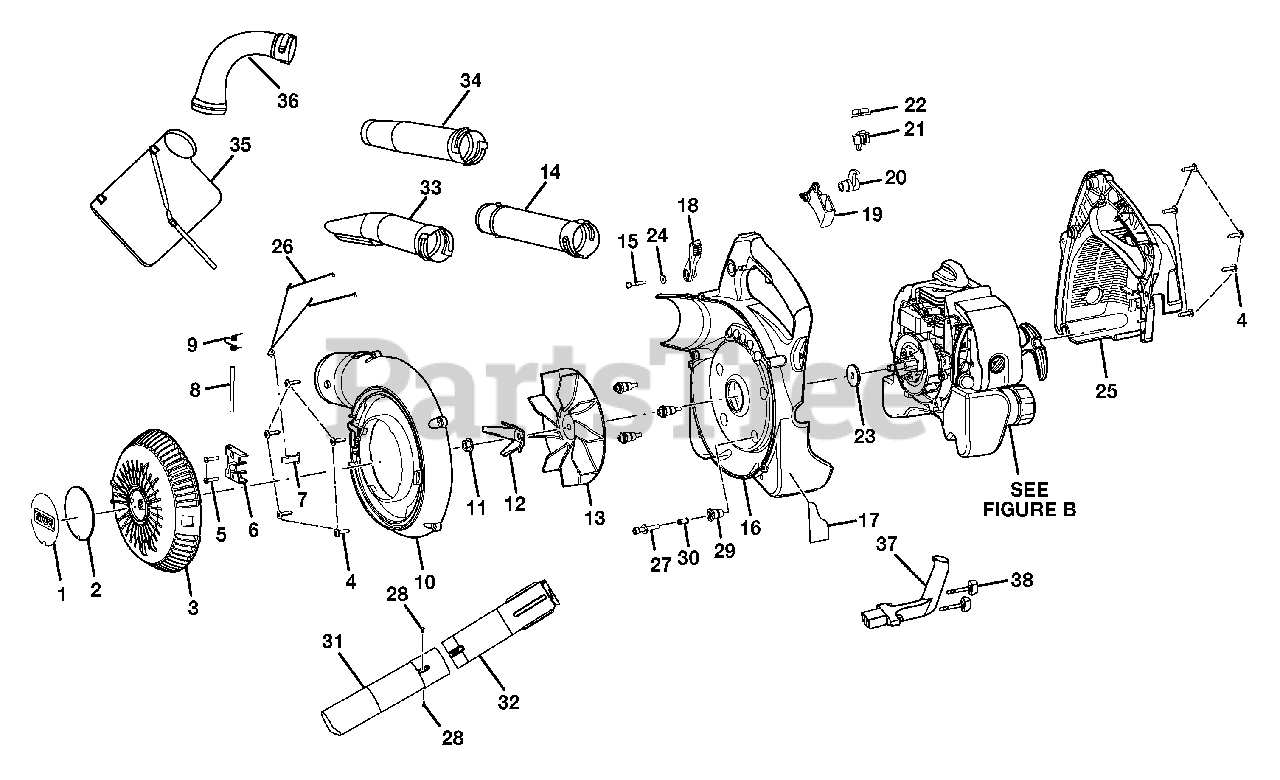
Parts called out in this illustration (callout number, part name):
1	VACUUM DOOR LABEL
2	VACUUM DOOR COVER
4	SCREW (#10-14 X 7/8 in.)
5	SCREW (#8-14 X 16.3 mm)
6	VACUUM DOOR HINGE
7	KILL SWITCH ACTIVATOR LEVER
8	HINGE PIN
9	VACUUM DOOR SPRING
10	OUTER VOLUTE HOUSING
11	RETAINING WASHER NUT
12	BLADE-MULDER
13	24.5 CC BLOWER FAN
14	TUBE-UPPER BLOWER
15	SCREW (#8-14 x 50 mm)
16	HOUSING INNER VOLUTE
17	WARNING LABEL
18	CRUISE LEVER
20	TRIGGER LOCK
22	DUST COVER
23	WASHER-FAN SPACER
25	ENGINE SHROUD HOUSING
26	VACUUM DOOR KILL SWITCH
27	SCREW (M5 X 30 mm CAP HD.)
28	SCREW (10-14 X 1/2 in.)
29	VIBRATION ISOLATOR
30	AV BUSHING SLEEVE
31	TUBE-LOWER VACUUM
32	TUBE-UPPER VACUUM
33	TUBE NOZZLE
34	TUBE-LOWER BLOWER
35	VACUUM BAG ASSEMBLY
36	TUBE ELBOW
